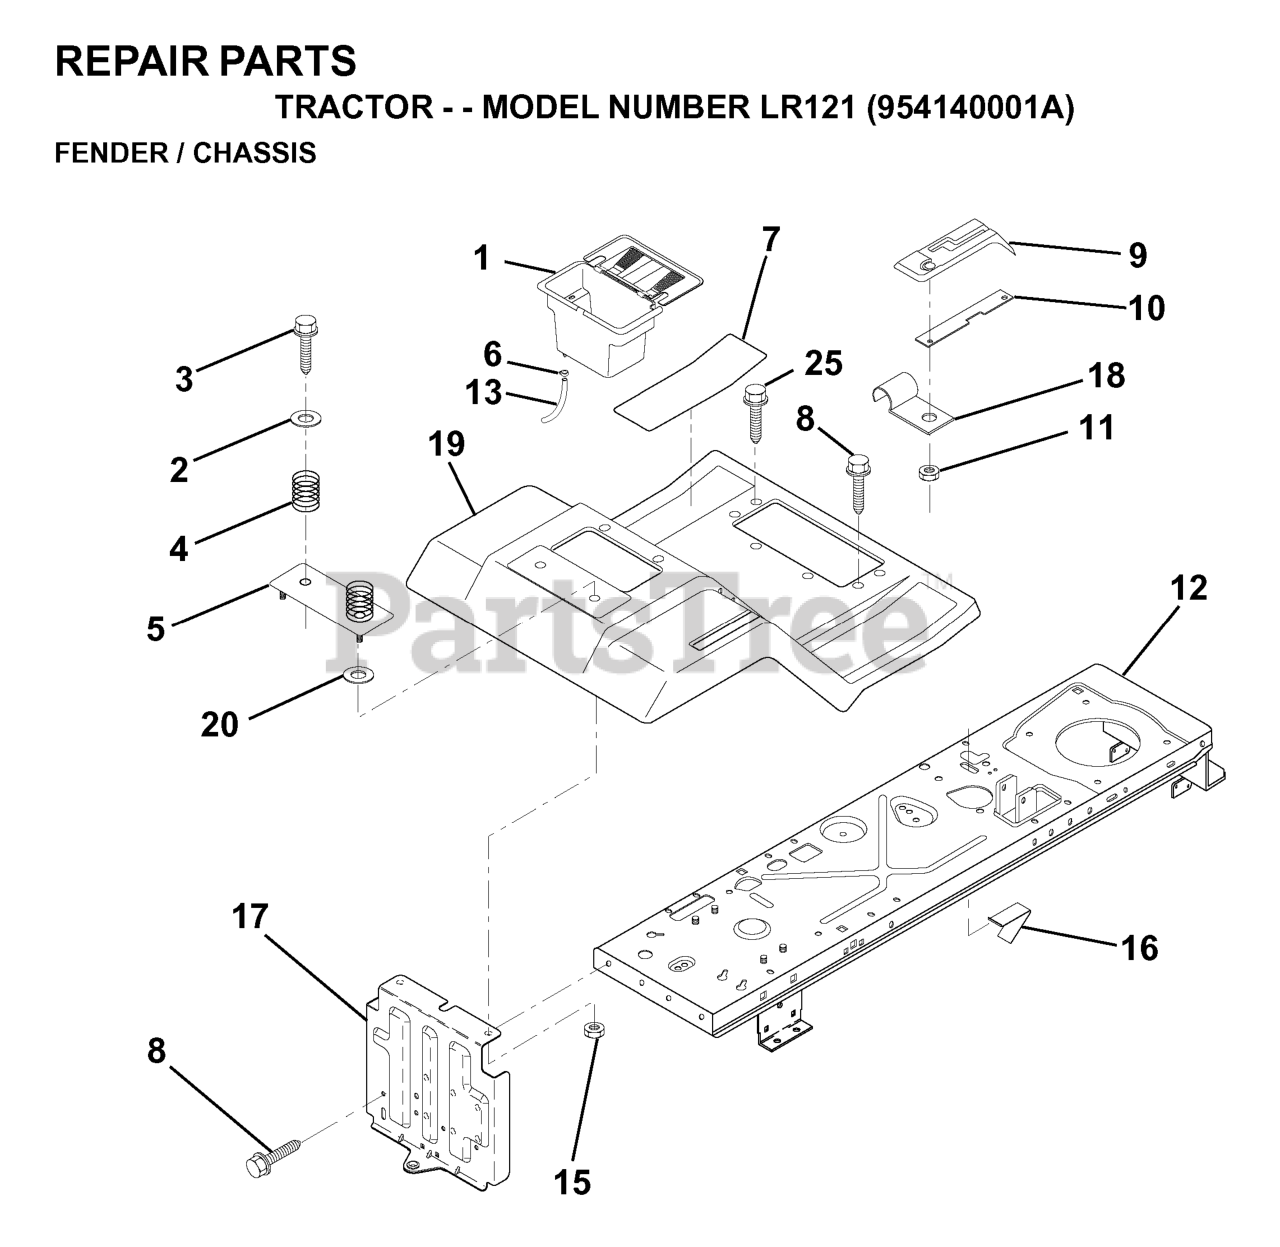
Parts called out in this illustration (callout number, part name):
1	CASE BATTERY MECH HINGE
2	WASHER
3	SCREW
4	SPRING COMPRESSION
5	PLATE ASM BATTERY
6	HOSE CLAMP T
7	PAD FOOTREST
8	SCREW.THDROL.5/16-18X3/4.TTY
9	CONSOLE SHT CONTR
10	BAR, SHIFT LOCK
11	NUT.PUSH.3/16
13	TUBE BATTERY DRAIN
15	Nut, Keps Blk Hex 1/4-20 UNC
16	SWITCH ACTUATOR
18	CLIP,INSULATOR
19	FENDER/FOOTREST
20	WASHER
25	Screw Hex Wsh Thdroll 5/16-18 x 1
